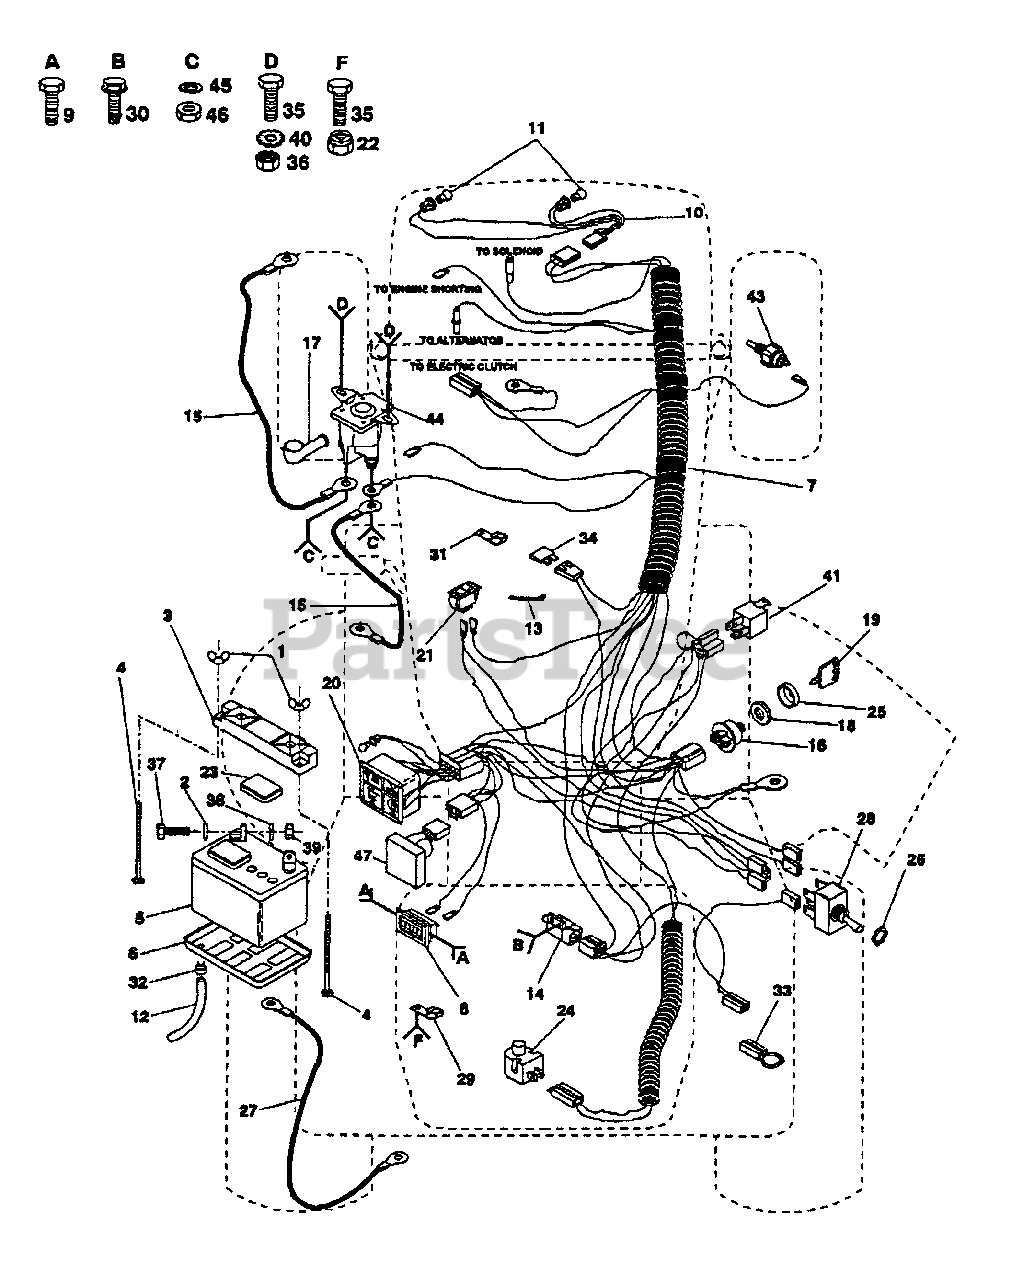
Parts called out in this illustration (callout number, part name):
1	Nut, Wing 1/4-20
2	Washer 9/32 x 5/8 x 16 Gauge
3	Guard, Terminal
4	Bolt, Carriage 1/4-20 x 7-1/2
5	Battery
6	Tray, Battery.
7	Harness, ignition
8	Motor, Hour
9	Screw #10-24 x 1/2
10	Harness, Socket Light
11	Bulb, Light
12	Tube, Tray Battery
13	Tie, Cable
14	Switch, Interlock (Clutch)
15	Cable, Battery (2)
16	Switch, Ignition
17	Cover, Terminal
18	Nut, Ignition
19	Key, molded
20	Package, Light
21	Switch, Light
22	Nut, Crownlock 1/4-20
23	Caps, Battery
24	Switch, Plunger
25	Bezel, Ignition
26	Nut, Hex
27	Cable, Battery
28	Switch, PTO
29	Clip, Insulated
30	Screw, Hex, Tap #10-24 UNC
31	Clip, Line Fuel
32	Clamp, Hose
33	Loop, Wire
35	Bolt, Hex 1/4-20 x 1/2 Grade 5
36	Nut, Hex, Keps 1/4-20
37	Bolt, Hex 1/4-20 x 3/4
38	Washer, Lock 1/4
39	Nut, Hex 1/4-20
40	Washer, Lock, External Tooth 1/4
43	Switch, Oil Sensor
44	Solenoid
45	Washer, Lock 1/4
46	Nut, Hex, Jam 1/4-20
47	Sensor, Low Voltage
49	Bulb, Light Package
